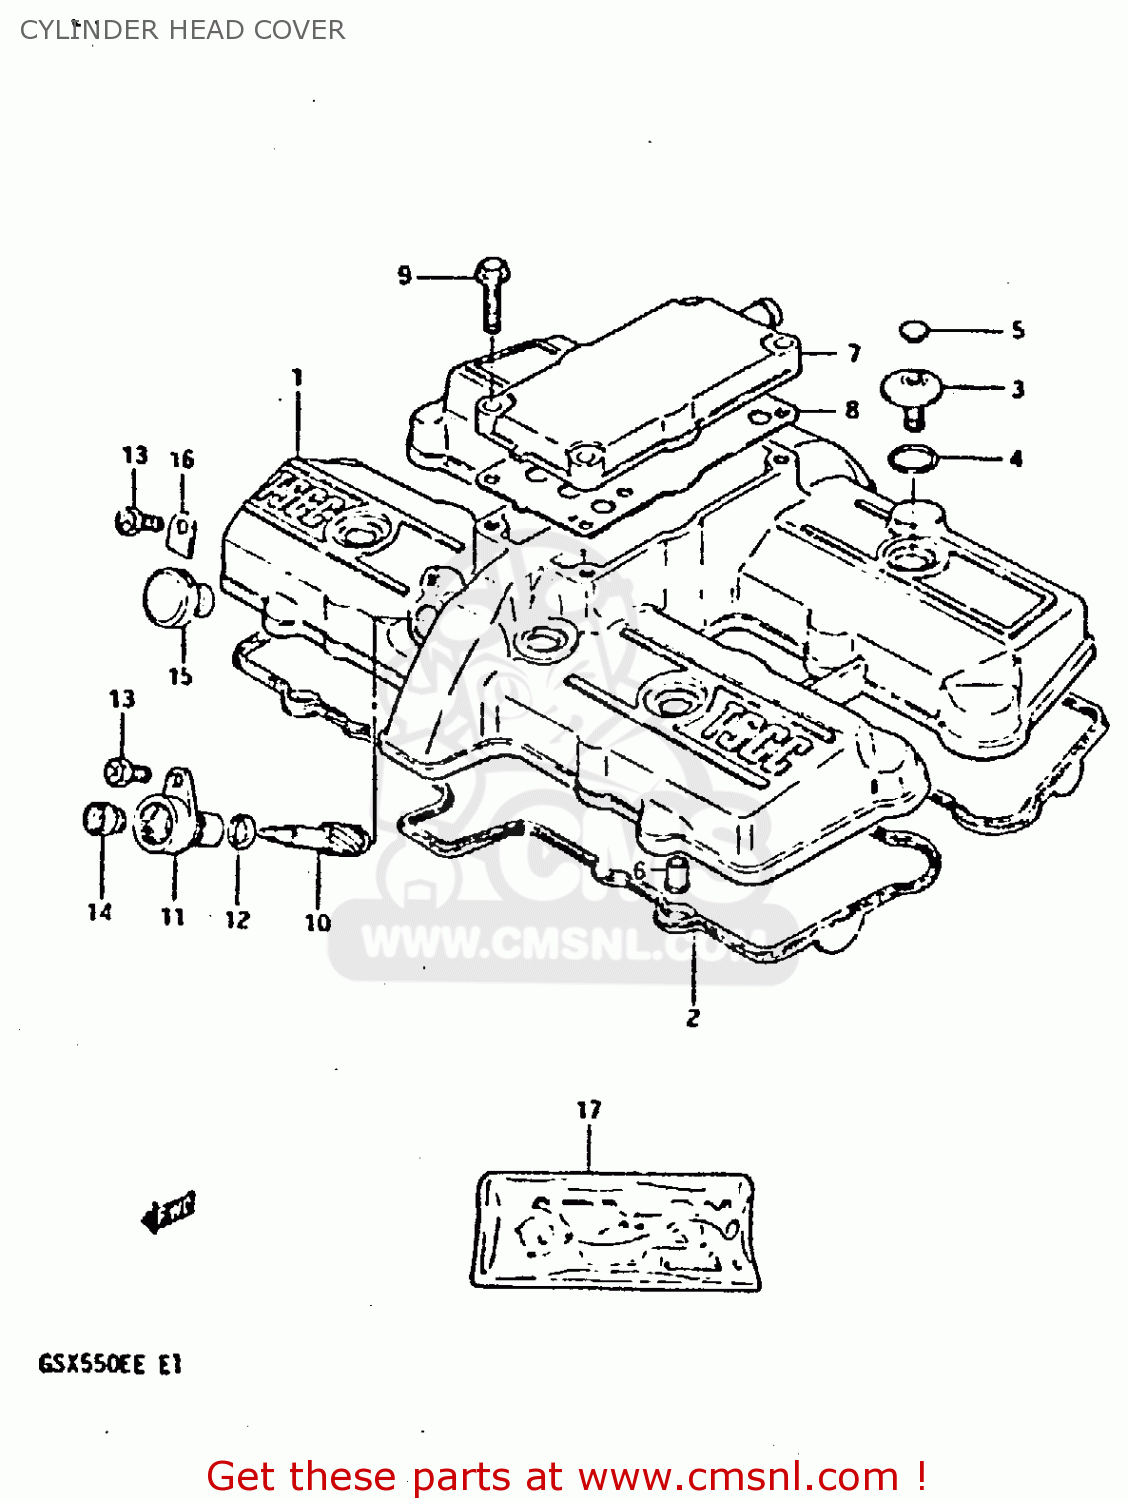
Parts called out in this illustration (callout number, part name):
1	COVER,CYLINDER HEAD
2	GASKET,CYL HEAD COVER (NAS)
3	BOLT(7X5.5)
4	O RING(D:1.9,ID:14.5)
5	CAP(OD:10)
6	PIN
7	COVER,BREATHER
8	GASKET (MCA)
9	BOLT
10	GEAR,TACHOMETER DRIVEN
11	SLEEVE,TACHOMETER DRIVE GEAR
12	SEAL,TACHOMETER DRIVEN
13	SCREW(5X12)
14	SEAL,OIL(5X12X8)
15	PLUG,TACH GEAR SLEEVE HOLE
16	PLATE,TACH DRIVE GEAR SLEEVE
17	GASKET SET (MCA)
